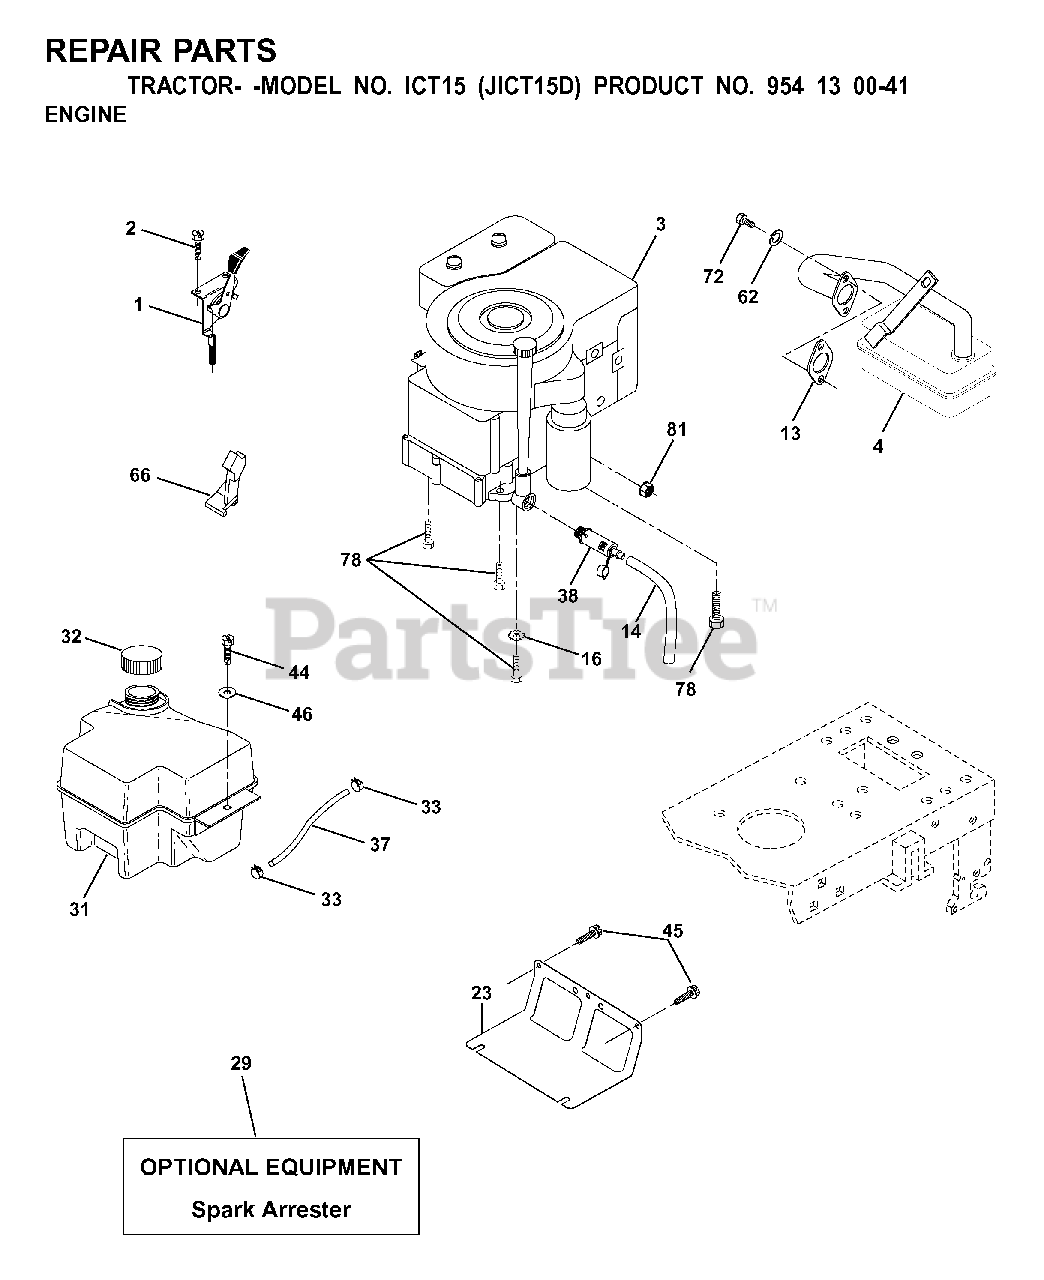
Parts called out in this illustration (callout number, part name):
1	THROTTLE CONTROL CABLE
2	SCREW LT
13	REPL BY 532 27 22-93
14	TUBE, DRAIN OIL ASM.
16	LOCKWASHER
23	SHEILD.BROWNING.DBR.GUARD
29	ARRESTER SPARK (OPTIONAL)
31	FUEL TANK
32	FUEL CAP
33	HOSE CLAMP
37	LINE.FUEL.20
38	PLUG, OIL DRAIN EASY
44	SCREW HEXWSHR 1/4-20X3/4
45	SCREW, 3/8-16X3/4
46	WASHER
62	LOCKWASHER
66	STOP THROTTLE
72	SCREW
78	SCREW.3/8-16
81	NUT
